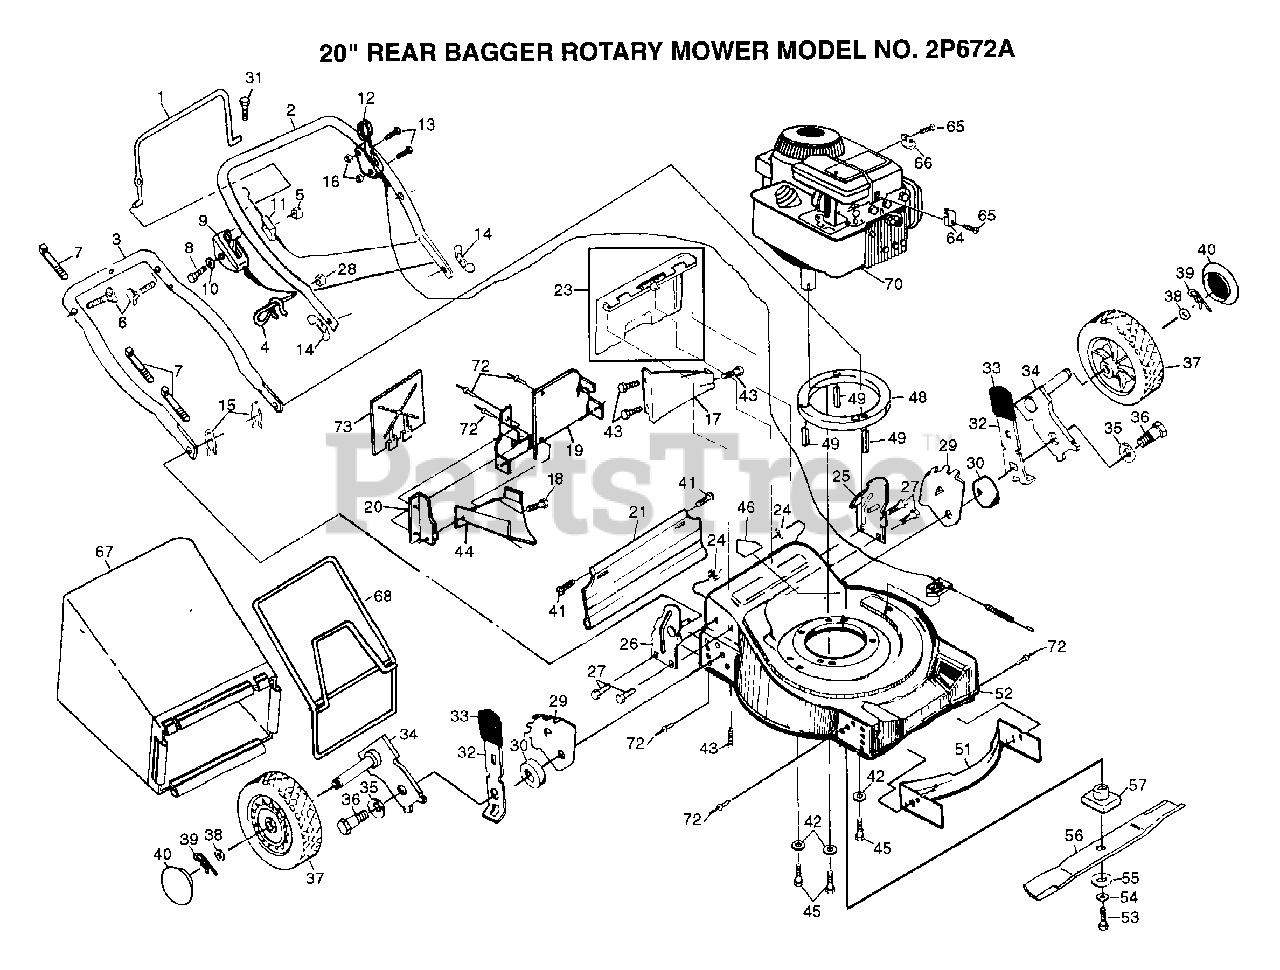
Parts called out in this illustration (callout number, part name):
1	CONTROL BAR
4	ROPE GUIDE
6	BOLT.HANDLE.LM
9	CONTROL THROTTLE
10	WASHER PM
11	"CABLE,ENG ZONE CO"
12	CONTROL DRV 20 FB
13	SCREW
14	"NUT,WING PM"
15	HAIRPIN COTTER
16	LOCKNUT
17	REAR BAFFLE
18	SCREW PM
19	PLATE.BACK.20RD
23	"KIT, REAR DOOR PM"
24	LOCKNUT PM
27	SCREW
28	NUT
29	BRACKET.ADJ.9POS.
31	"SCREW,PAN HD"
32	SPRING SELECTOR
33	KNOB PM
34	AXLE ARM
35	"WASHER, BELLEVIL."
38	WASHER
39	RETAINER CLIP PM
40	HUB CAP
41	HINGE SCREW
43	SCREW
44	DISCHARGE GUARD
45	SCREW
46	DECAL HYT
48	ENGINE SPACER
52	KIT.HSG.20RD.FWBD
53	SCREW
54	LOCKWASHER
55	"WASHER,HARDEN"
57	ADAPTOR.BLADE.LM
64	CABLE CLAMP
65	SCREW PM
66	GUIDE CLIP PM
67	GRASS BAG
68	CATCHER FRAME
72	BLIND RIVET
73	MULCHER PLATE
